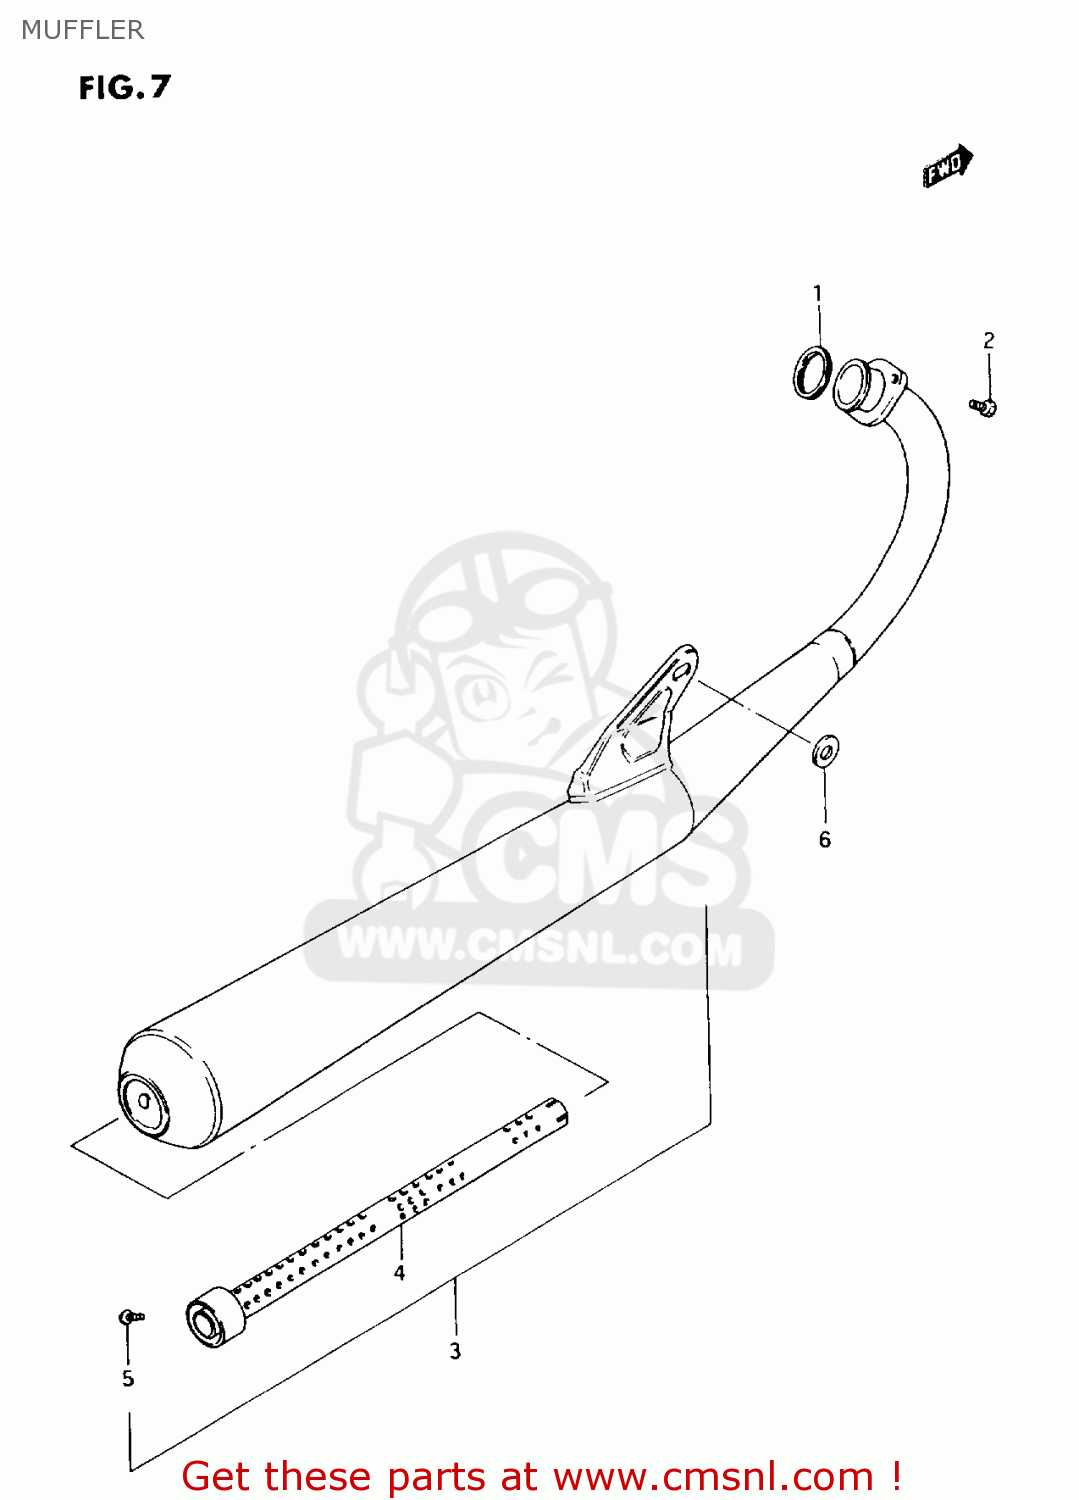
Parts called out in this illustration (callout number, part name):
1	GASKET,EXHAUST PIPE (NAS)
2	BOLT
3	MUFFLER ASSY
4	PIPE,BAFFLE
5	SUZUKI PART
6	WASHER (12.5X24X3.2)
